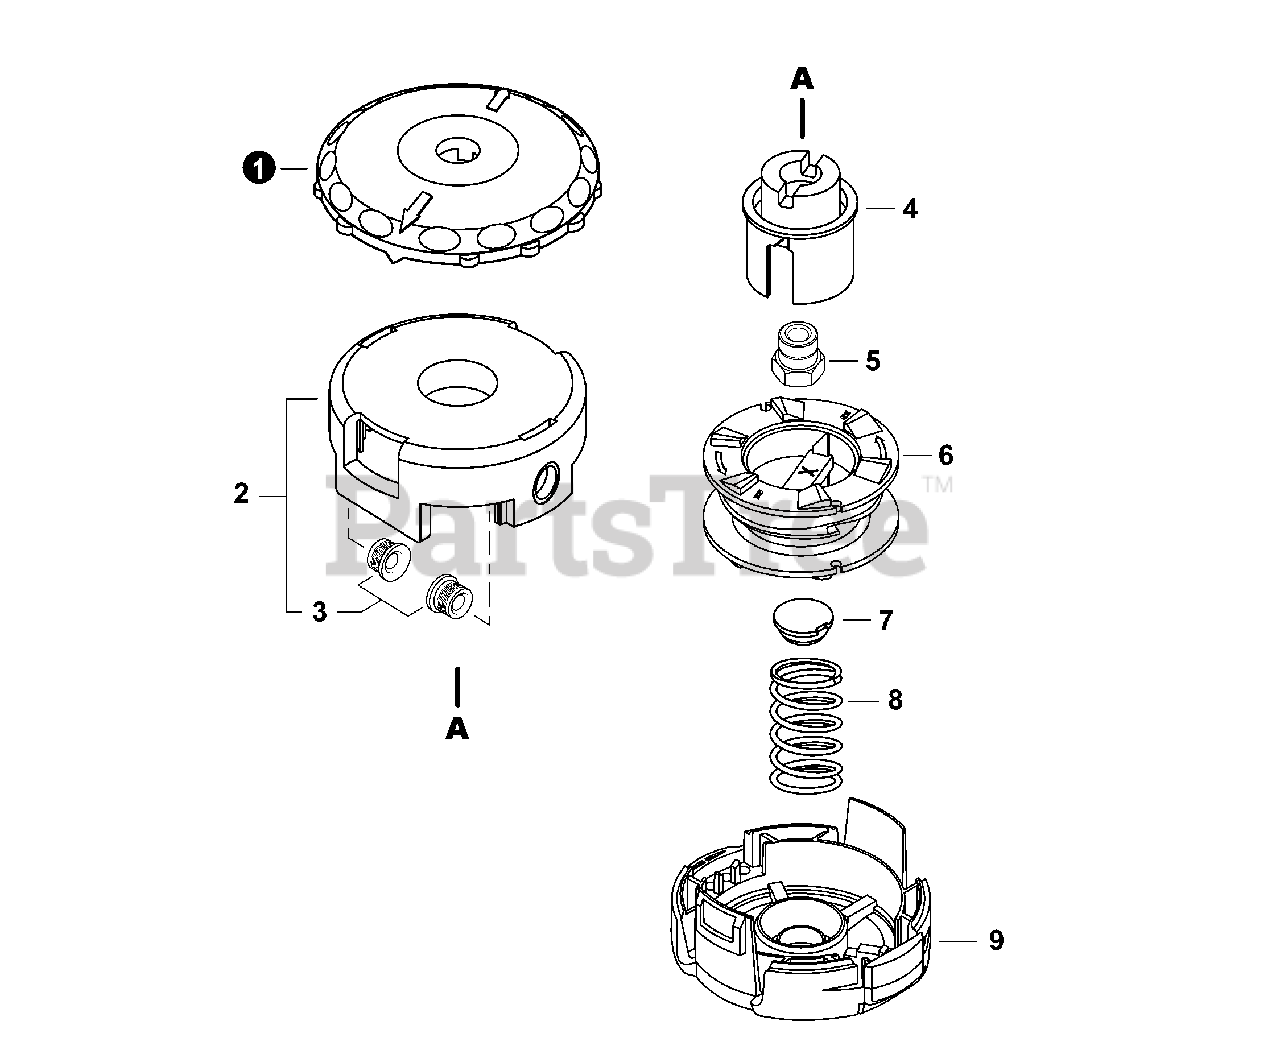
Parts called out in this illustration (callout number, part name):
2	HOUSING ASSY, SPOOL
4	HUB (LH) BLACK
5	BUSHING M10×1.25 LH GOLD
7	CAP, SPRING
8	SPRING, GOLD
9	COVER, SPOOL
